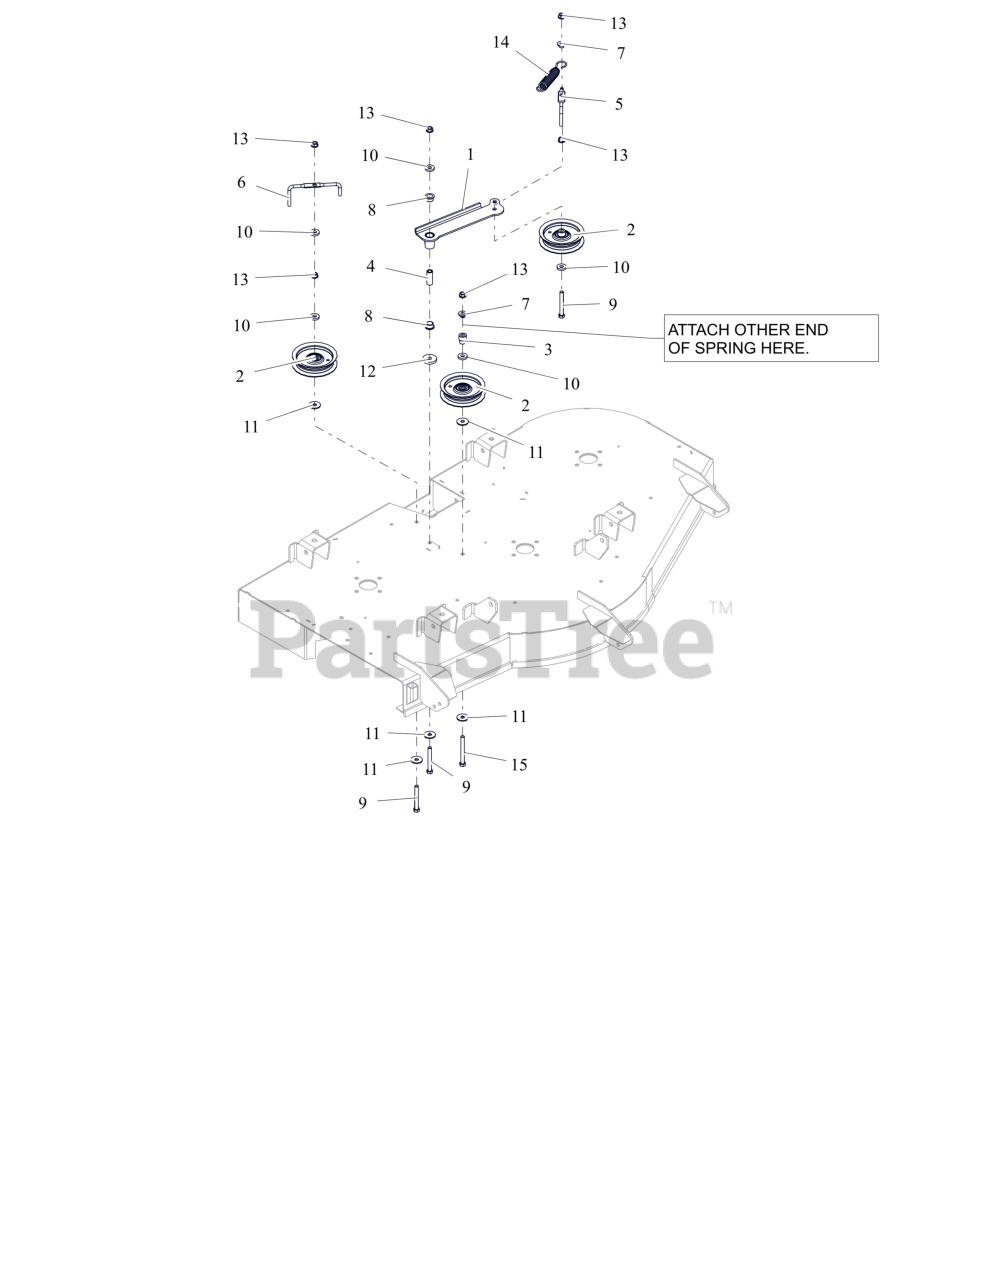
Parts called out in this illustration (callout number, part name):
1	WLDMT- IDLER ARM-52"
2	IDLER, FLAT - 4.06" X .75"
3	BUSHING, IDLER (P/M)
4	SPACER, .375IDX.625ODX1.66 PM
5	WIREFORM, BELT FINGER
6	BELT FINGER
7	BSHG-FLG .385X.500X.875X.406
8	BSHG-FLG, .625X.750X.500X1.00
9	BLT, HEX .38-16X3.00F G5 ZCC
10	WSHR, FLT .406X1.00X.188 ZCC
11	WSHR FL STL .406X1.25X.10ZC120
12	WSHR, FLT .406X1.50X.245 ZCC
13	NUT-LK-CTR-FLG .375-16 GF ZCC
14	SG-TENS .135X.98X6.0 WLD 62
15	BLT, HEX .38-16X3.50 G5 ZCC
